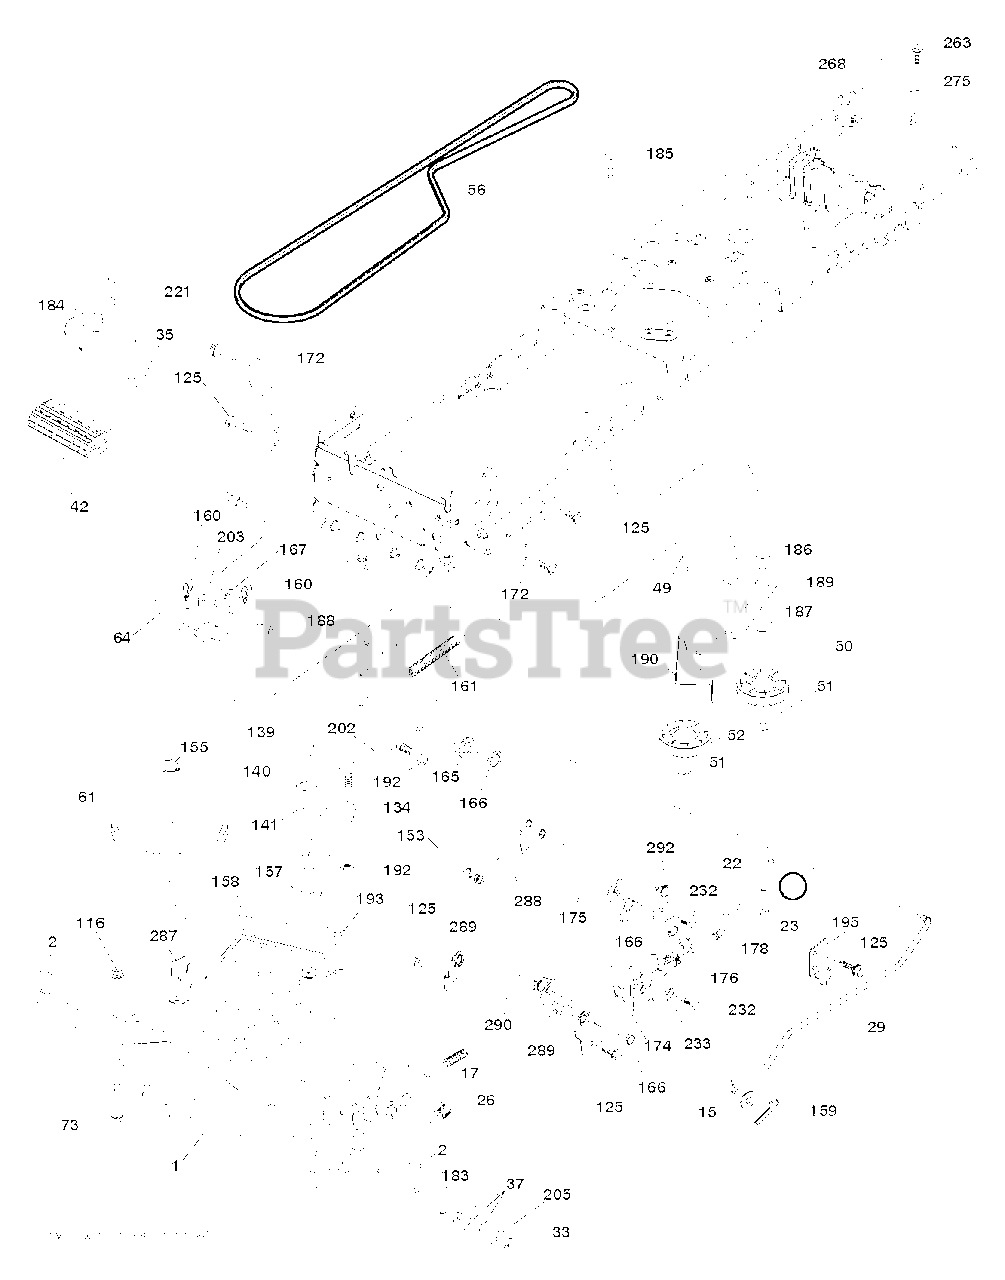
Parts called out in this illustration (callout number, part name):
17	SPRING.BRAKE.PEERLESS.TEX
22	SHIFTER.ASM.HANDLE.SRD
23	KNOB.DUCKHEAD.1/2
26	SPRING.BRAKE.RTN.GR.DR
29	ROD.BRAKE.PEERLESS
35	ROD.BRAKE.PARKING.LT.T
42	PEDAL COVER T
49	BOLT
50	IDLER.FLAT.910.OFFSET
51	NUT LOCK FLG 3/8-16 UNC
52	IDLER.V-GROOVE.910.OFFSET
56	BELT, V GROUND DRIVE 95 25
64	SHAFT.ASM.PEDAL.BRAKE.
116	NUT LOCK HEX FLANGE 5/16-18
125	SCREW
139	BOLT 1/4-28X3/4
140	LOCKWASHER
141	WASHER LT
153	RETAINER M
155	RETAINING RING LT
157	WASH-SHFT PLT LT
158	KEEPER.PMS.18/20.D4365
159	COTTER PIN
160	RETAINER CLIP
161	SPRING, RETURN LT
165	BUSHING.SHAFT.BRAKE.HAND
167	LATCH.BRAKE.SPRING
172	STRAP.TRQ.LH.GEAR.DRIV
174	NUT.PUSH.500.2006
175	SHAFT ASM SHIFT
176	ARM.CLEVIS.ROD.SHIFT
178	SPRING.TORSION.LIFT.HANDLE
184	HANDLE.PARKING.BRAKE.LTTEX.667
186	SPACER.RETAINER
187	WASHER 12/32X2X10GA
188	LINK.CLUTCH.GROUND.DRIVE
189	BELLCRANK.GROUND.DRIVE.TEX.
190	KEEPER.BELLCRANK.DRIVE
192	NUT LOCK CENTER 1/4 -28 FNTHD
193	SCREW 5/16"
195	BRKT.ROD.BRAKE.PEERLES
202	LINK.SHIFT.PMST.18"
203	WASHER
221	RETAINER.SPRING.CLIP.H
232	BOLT FIN HEX 7/16-14 X 1
233	WASHER SERRATED
263	SCREW, 3/8-16X3/4
275	WASHER
287	KEEPER.PULLEY.T/A.7.04
288	LINK.SHIFT.SLAVE.SRD
289	BRACKET.SUPPORT.SHIFT.OUTER
290	SHAFT.ASM.SHIFT.REAR.SRD
292	PLATE.ASM.SHIFT.FWD.SRD
